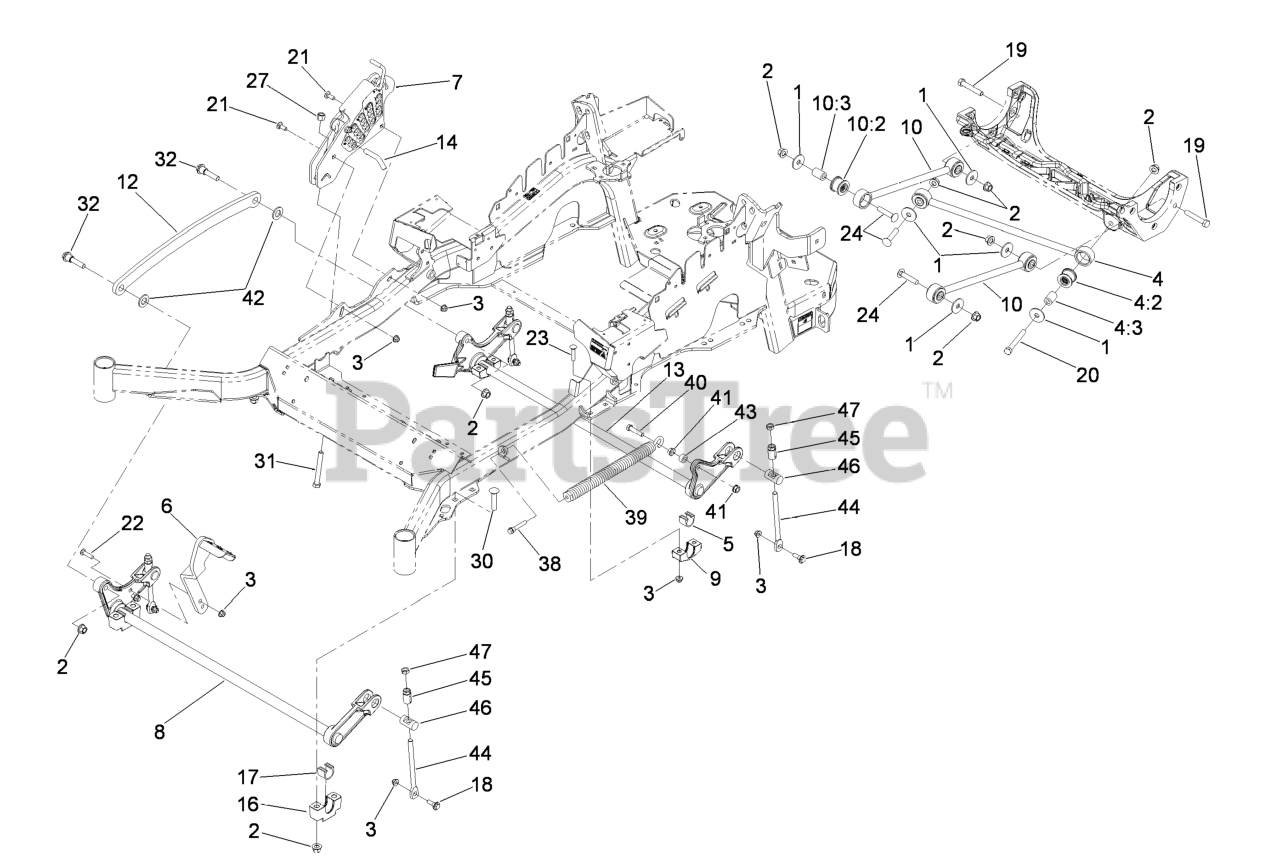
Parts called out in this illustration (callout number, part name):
1	WASHER-THRUST
2	Nut-Lock 1/2-13
3	NUT-HF, NI
4	PANHARD ROD ASM
4:2	BUSHING-SUSPENSION, RUBBER
5	BEARING-CROSS SHAFT, REAR
6	LEVER-FOOT
7	HOC ASM
10	DECK STRUT ASM
10:2	BUSHING-SUSPENSION, RUBBER
12	LINK-LIFT, DECK
13	LIFT-DECK, REAR
14	PIN-HOC
16	SUPPORT-CROSS SHAFT, BEARING
17	BEARING-CROSS SHAFT, FRON
18	SCREW-SHOULDER, HHF
19	SCREW-HH
20	SCREW-HH
21	BOLT-CARR
22	SCREW-CARR
23	SCREW-CARR
24	SCREW-CARR
27	NUT-LOCK, NI
30	Bolt-Carriage 1/2-13 X 2 1/2 Spl Neck
31	BOLT-TAP
32	SCREW-HHF, SHOULDER
38	BOLT-SHOULDER
39	SPRING-EXTENSION
40	SCREW-HH
42	WASHER-FLAT
44	LINK-ADJUSTER, DECK LIFT
45	ADJUSTER-LIFT, DECK
46	TRUNNION
47	NUT-JAM
